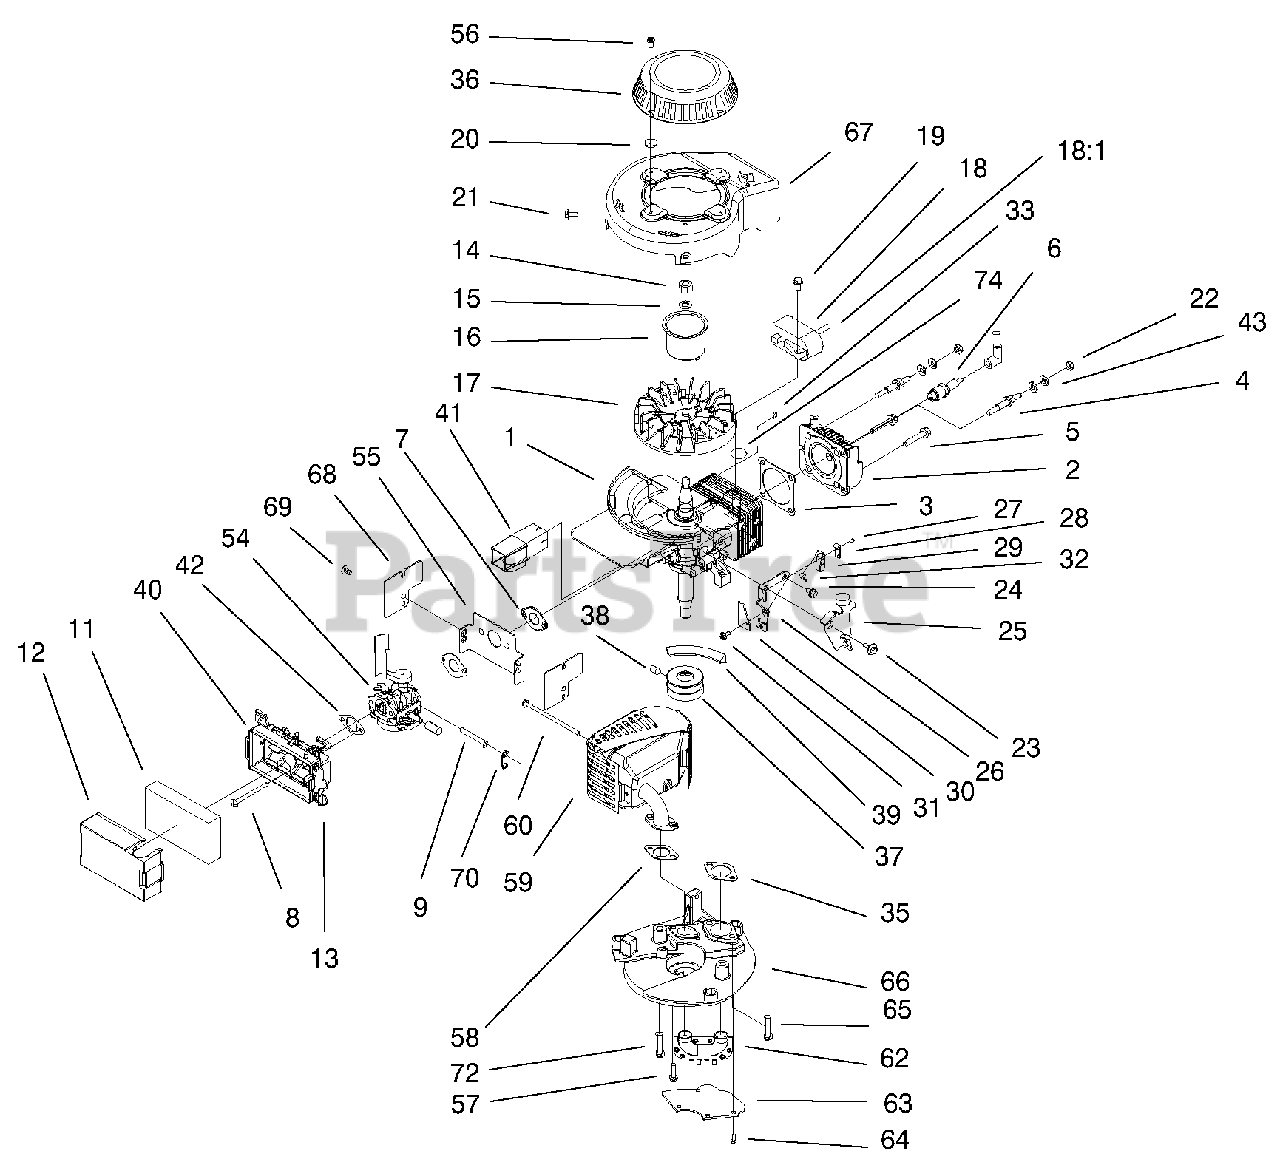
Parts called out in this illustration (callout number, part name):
1	Short Block ASM
2	Head-Cylinder
3	Gasket-Head
5	Bolt-Head
6	Plug-Spark
7	Gasket-Intake
9	Hose-Primer
11	Filter-Air
12	Cover-Air Filter
13	Retainer-Filter Cover
15	Washer-Lock
16	Hub-Starter
17	Flywheel
18	Module-Ignition
18:1	Lead-High Tension Clip
21	Screw-HH
23	Screw-Shoulder
24	Screw-HWH
25	Brake Plate ASM
26	Plate-Brake
27	Rivet-Plastic
28	Strap-Insulation
29	Strap-Ground
30	Stop-Ground Strap
32	Lead Wire-Brake Switch
35	Gasket-Exhaust
36	Starter ASM
38	Screw-Set
40	Air Base ASM
41	Tunnel-Inlet
42	Gasket-Filter
43	Washer-Belleville
54	Carburetor ASM With Gaskets
55	Shield-Carburetor
59	Muffler And Guard ASM
60	Bolt-Console
62	Pipe-Transfer
63	Cover-Muffler
64	Screw-HH
65	Screw-HH
66	Plate-Mounting
67	Assembly-Shroud
68	Shield-Gov. V (Intl)
69	Screw #10 Six Lobed
70	Hose-Retainer
74	Strap-Tie
